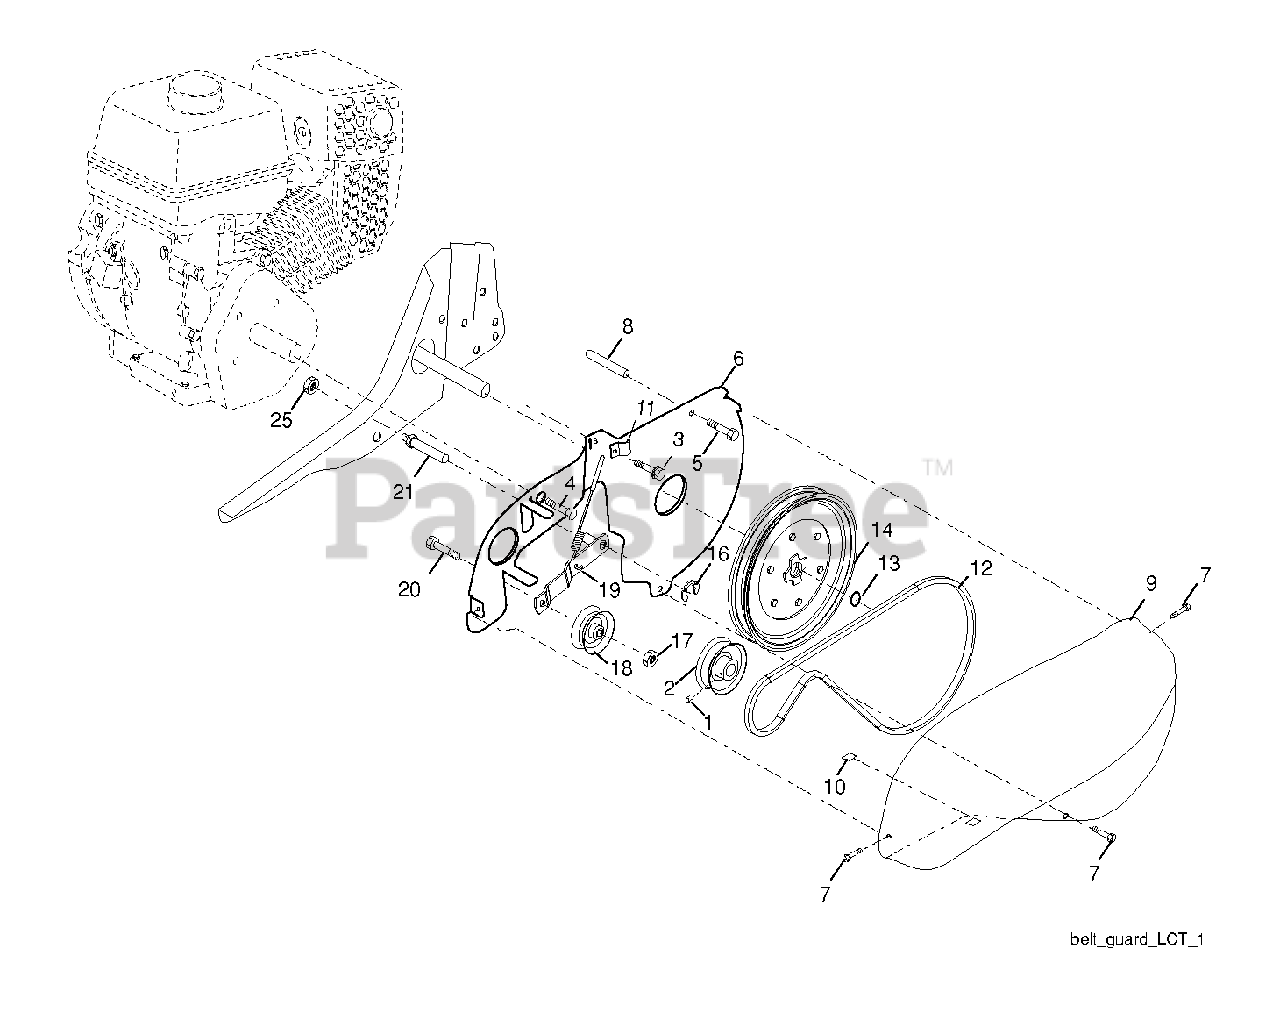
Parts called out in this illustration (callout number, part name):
1	SET SCREW
2	CONDUIT CLIP T
5	BOLT, THD ROLLER 1/4-20 X 2-1/
6	SHIELD, INNER BELT GUARD
7	SCREW.HEX.WSH.SLT.#10-24X.50
9	BOLT
10	PAD IDLER TI
11	CONDUIT CLIP T
12	V BELT STD
13	RETAINING RING LT
14	SHEAVE.TRANS
16	RETAINING RING LT
17	NUT
18	PULLEY, IDLER
19	ARM, IDLER
21	SHAFT.IDLER.TILLER
25	JAM NUT TI
